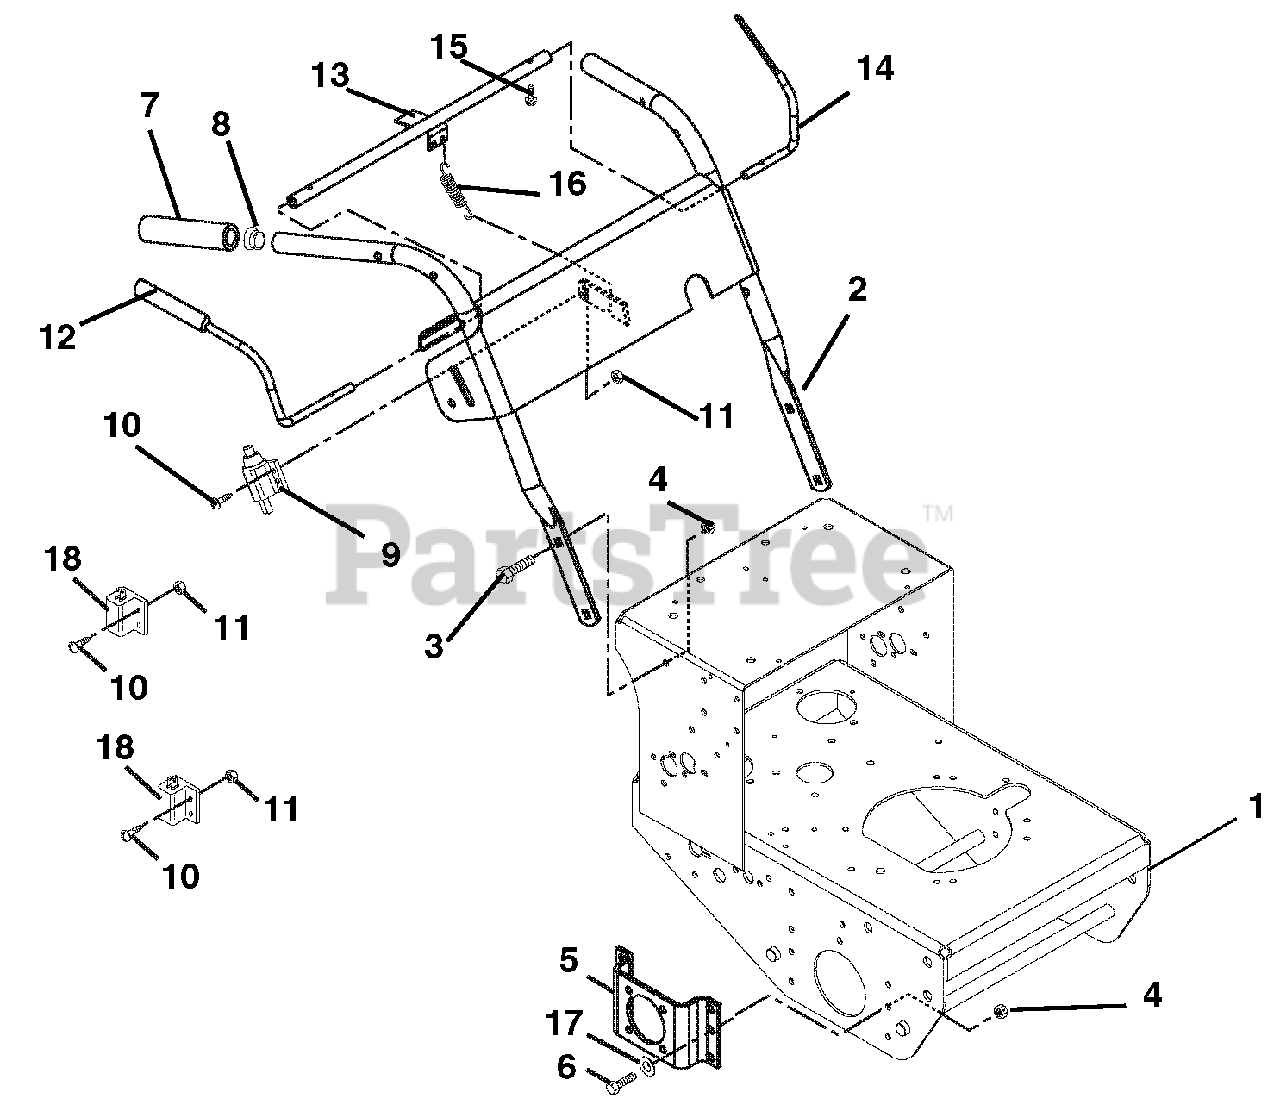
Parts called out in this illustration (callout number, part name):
1	Kit-Frame with Decals
2	Kit-Handlebar with DecalsHR15 (105 - 107, 113, 312)
3	Bolt-Hex .38-16 x 1.00 Grade 5
4	Nut-Locking-Nylon .38-16
5	Bracket, Wheel Motor Left Hand (105, 107, 108, 312)
6	Bolt-Hex .38-16 x 1.00 Grade 5
7	Grip, Handlebar
8	Caplug, Handlebar
9	Switch - Double Pole (105 - 109, 113, 312)
10	Screw-Machine 10-24 x .75 Hex Washer Head (105 - 109, 113, 312)
11	Nut-Locking-Nylon 10-24 with Insert (105 - 109, 113, 312)
12	Lever, Right Hand-Operator Presence
13	Weldment, Pivot Tube
14	Lever, Left Hand-Operator Presence
15	Screw-Tapping 8-32 x .50 Hex Washer Head
16	Spring-Tension .047 x .438 x 1.45
17	Washer-Flat-Steel .406 x .812 x .065 (105 - 109, 113, 312)
18	Switch- Single Pole (N.O.)
